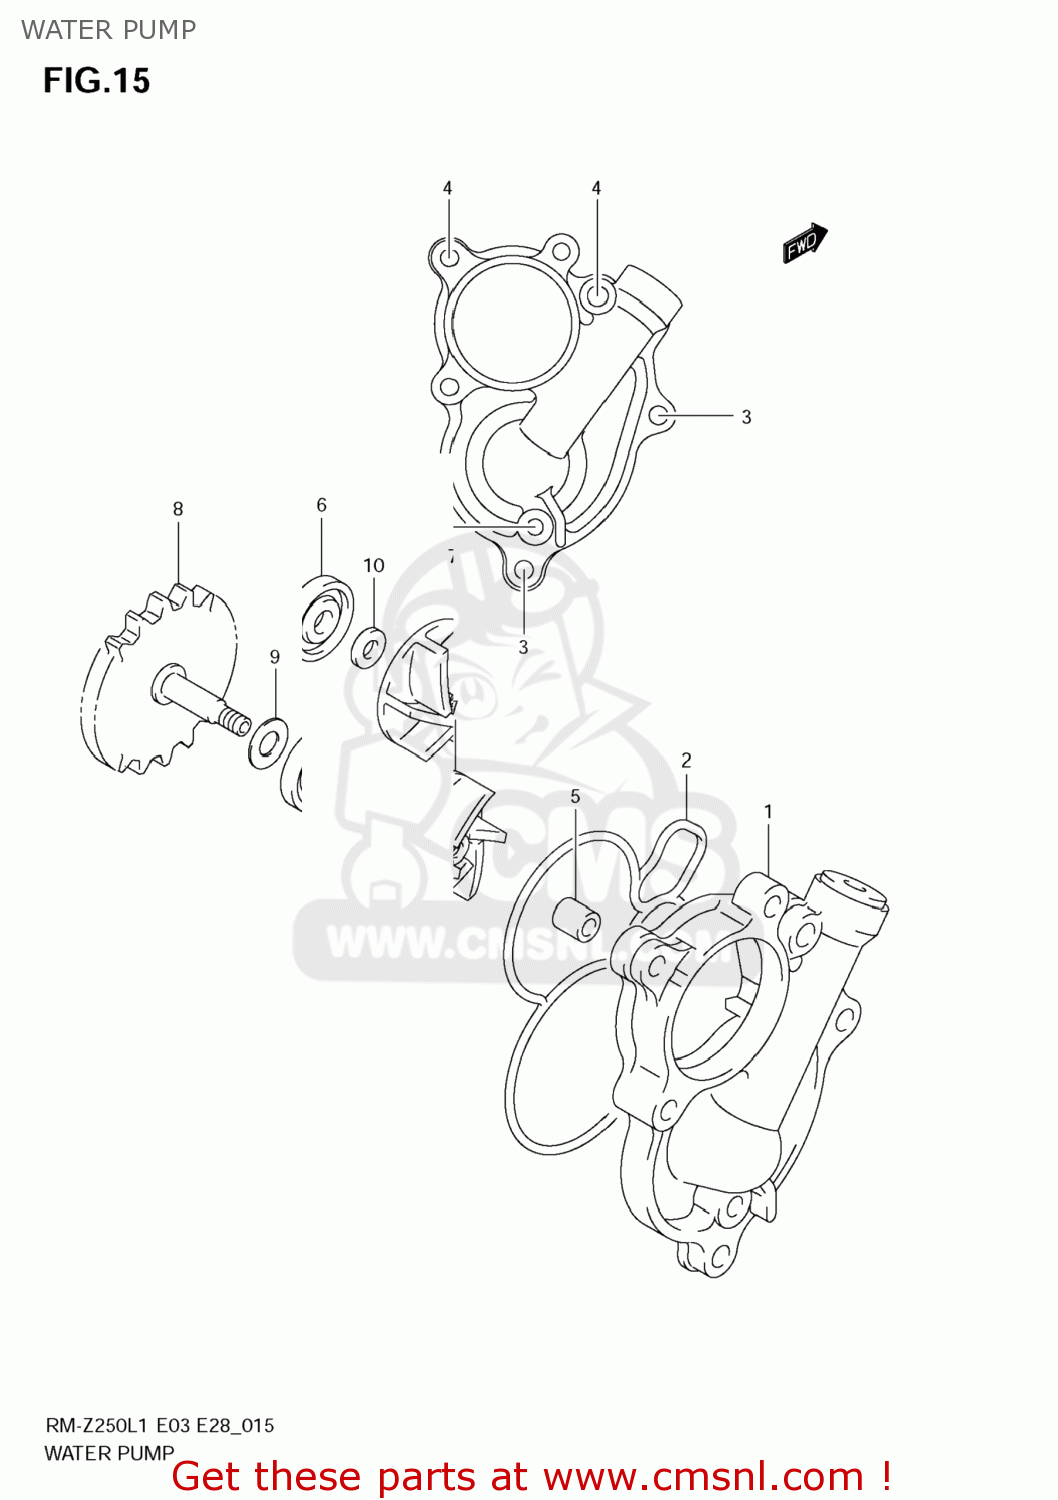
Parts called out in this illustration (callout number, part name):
1	CASE,WATER PUMP
2	O RING,WATER PUMP CASE
3	BOLT
4	BOLT
5	PIN
6	SEAL,WATER PUMP OIL
7	IMPELLER,WATER PUMP
8	SHAFT,WATER PUMP
9	SHIM(8X18X0.5)
10	SHIM(6X14X1)
11	BOLT
12	GASKET(5.8X13X1.2) (NAS)
